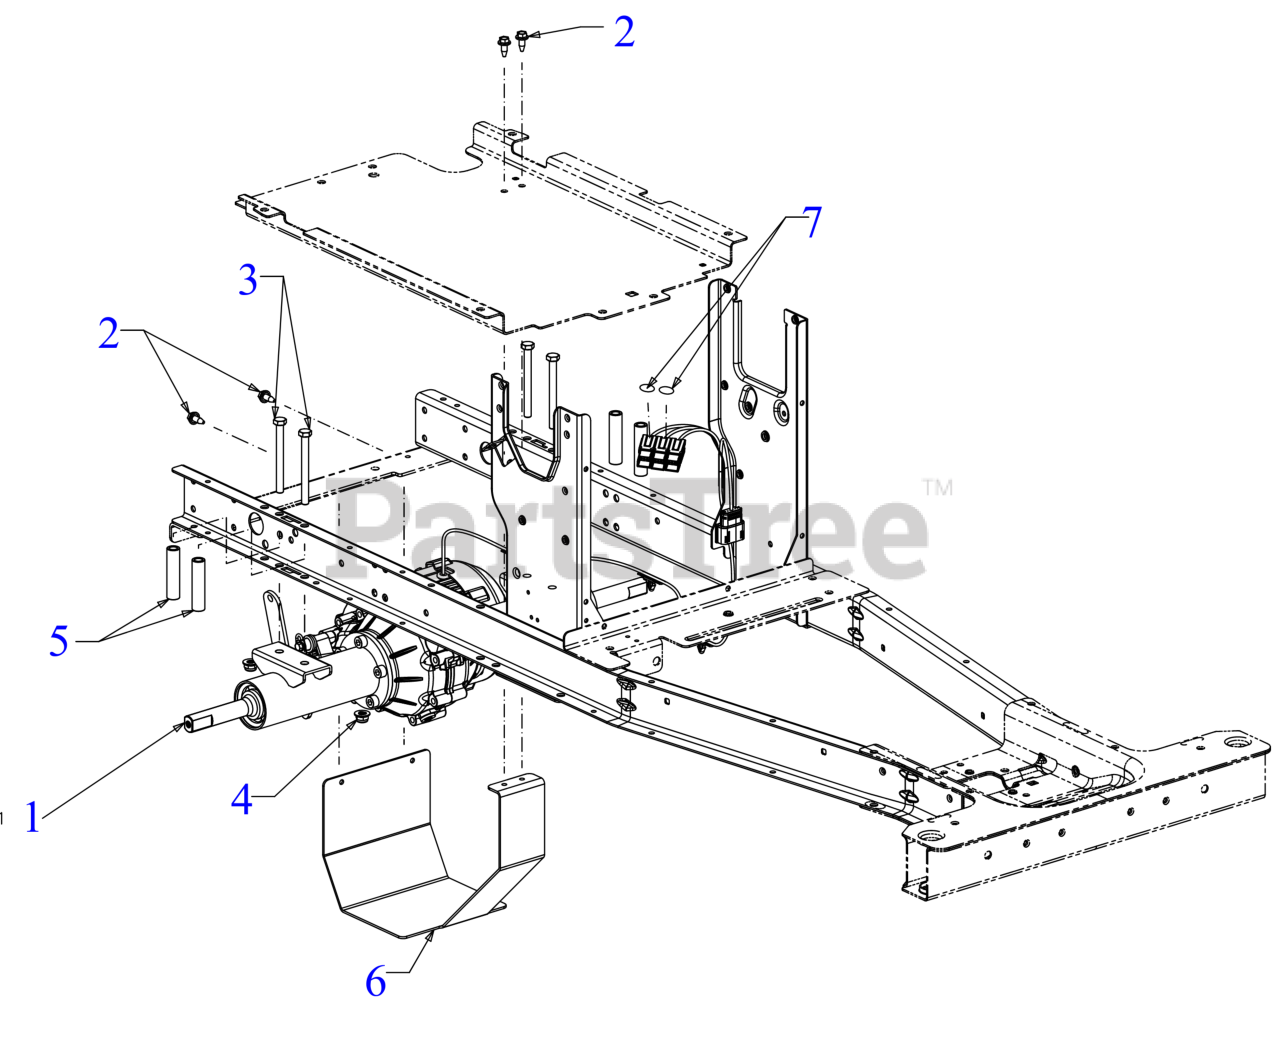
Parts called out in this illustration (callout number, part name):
1	TRANSMISSION ASSEMBLY
2	SCREW 1/4-20X.625
3	SCREW 5/16-18 x 3.25 GR5
4	FLANGE LOCK NUT 5/16-18
5	SPACER (.35 x .55 x 2.345)
7	RATCHET CLIP
